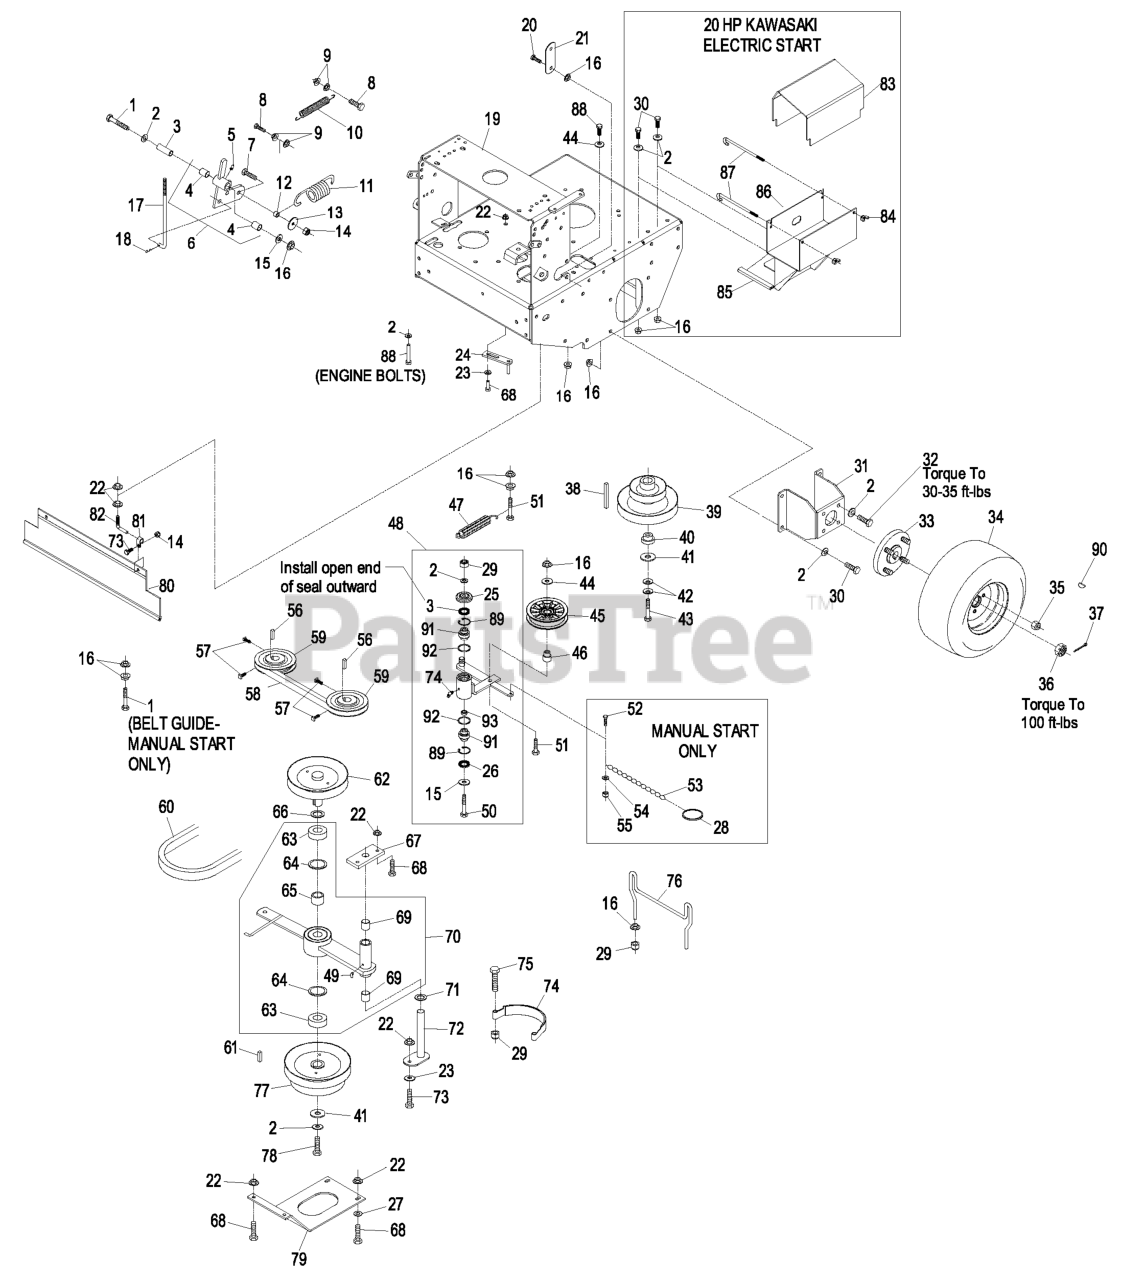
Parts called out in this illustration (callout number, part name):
1	SCREW-HH
2	WASHER-BELLEVILLE
3	SEAL-LIP, SINGLE
4	SLEEVE-BEARING
5	FITTING-GREASE
6	ASM,PIVOT W/BUSHINGS
7	SCREW-HH
8	SCREW-HH
10	SPRING,EXTENSION
11	SPRING,EXTENSION
12	SPACER,CLUTCH ANCHOR
14	NUT-LOCK, NI
15	WASHER-FLAT
16	NUT-HHF, WHIZ
17	LINKAGE,LOWER
18	PIN-COTTER
19	KIT,TTHP ENG DECK
20	SCREW-HH
21	ARM-LIFT, DECK
23	WASHER-SPRING
24	GUIDE-BELT
25	GUARD-TOP
26	SEAL-LIP, DOUBLE
27	WASHER-FLAT
28	RING-SPLIT
29	NUT-LOCK, NI
30	SCREW-HH
31	WLD,MOTOR MOUNT 36
32	SCREW-HH
34	WHEEL AND TIRE ASM
35	NUT-LUG
36	NUT-HEX, SLOTTED
37	PIN-COTTER
38	KEY,MACH 1/4X1/4X2-5/8
39	SHEAVE, DRIVE
40	BUSHING,CLUTCH KEEPER
42	WASHER-SPRING
43	SCREW-HH
44	WASHER-FLAT
45	PULLEY-IDLER, FLAT
46	BUSHING-IDLER
48	KIT,PUMP IDLER ARM TTHP
49	FITTING-GREASE
50	SCREW-HH
51	SCREW-HH
52	SCREW-HSH
53	CHAIN-LINK, TWIST
54	WASHER-FLAT
55	NUT-LOCK, NI
57	SCREW-SET
58	BELT,COG A 50.55
59	SHEAVE ASM
60	BELT,B-38.0
62	SHEAVE, W/ SHAFT
63	BEARING,CLUTCH SHAFT
64	RING-SNAP
65	SPACER,CLUTCH BEARING
66	WASHER-SPACER
67	PLATE-CLUTCH PIVOT
68	SCREW-HH
69	SLEEVE,BEARING
70	ASM,CLUTCH ARM W/BEARING
71	WASHER-SPACER
72	WLD,PIN PIVOT
73	SCREW-HH
74	BAND,BRAKE BLADE
75	SCREW-HH
76	GUIDE,BELT (PLTD)
77	SHEAVE,6.13 W/HUB
78	SCRW,CAP HH
79	PLATE-GUARD
80	SHIELD-DRAG
81	CLIP-LOOM
82	MOUNT,DRAG SHIELD
83	COVER,BATTERY W/DECAL
84	WINGNUT
85	TRIM-LOK
86	ASM,BATTERY STAND W/TRIM
87	BOLT - HOLD DOWN
88	SCREW-HH
89	RING-SNAP
90	KEY-WOODRUFF
91	BEARING-SPHERICAL
